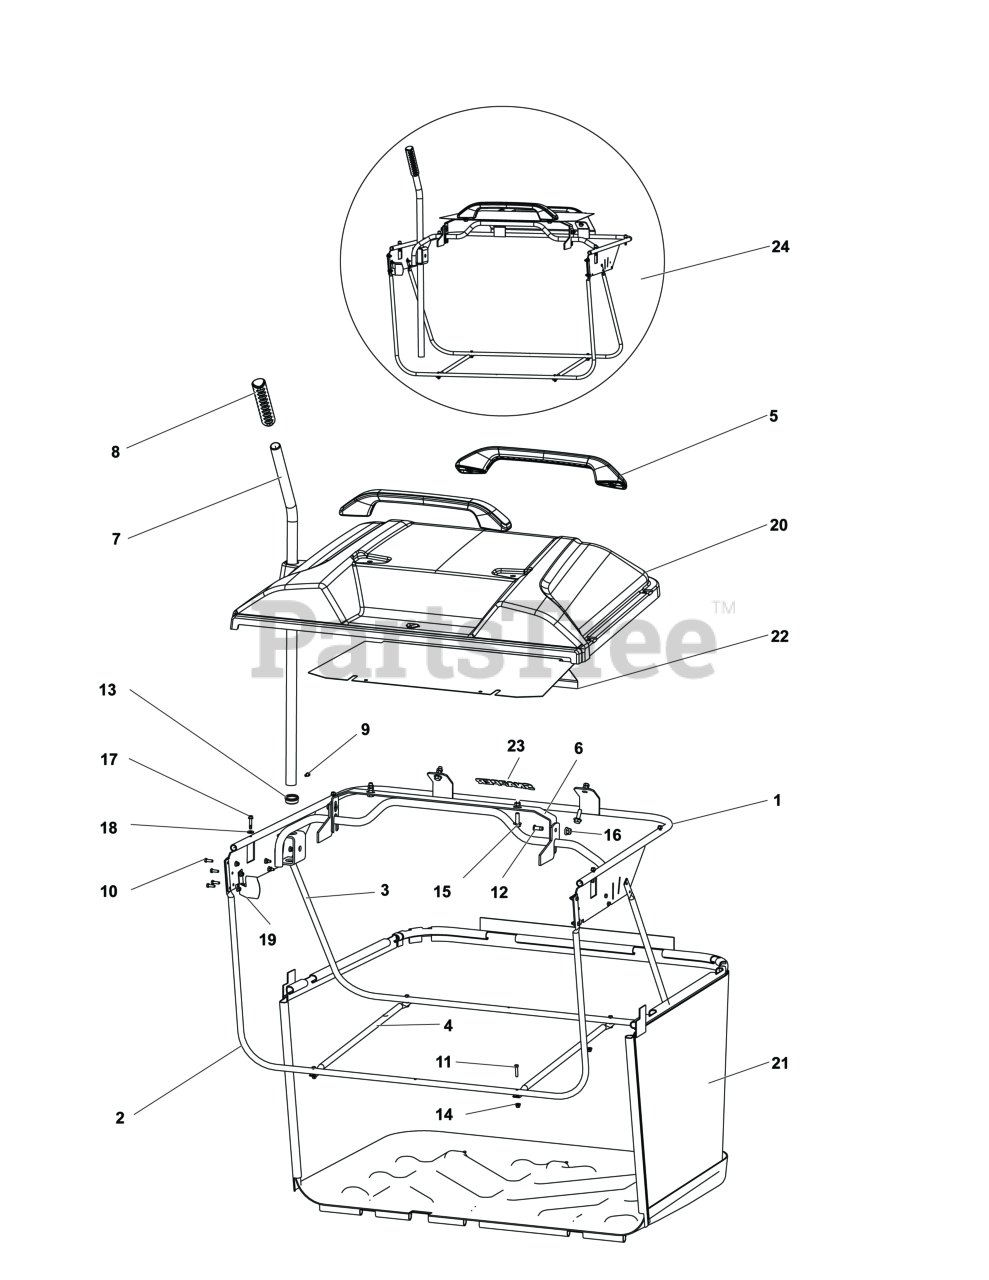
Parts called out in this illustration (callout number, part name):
4	TUBE, Connecting
6	PLATE, Reinforcement
21	COLLECTOR
23	DECAL, Brand
24	CATCHER, Grass
